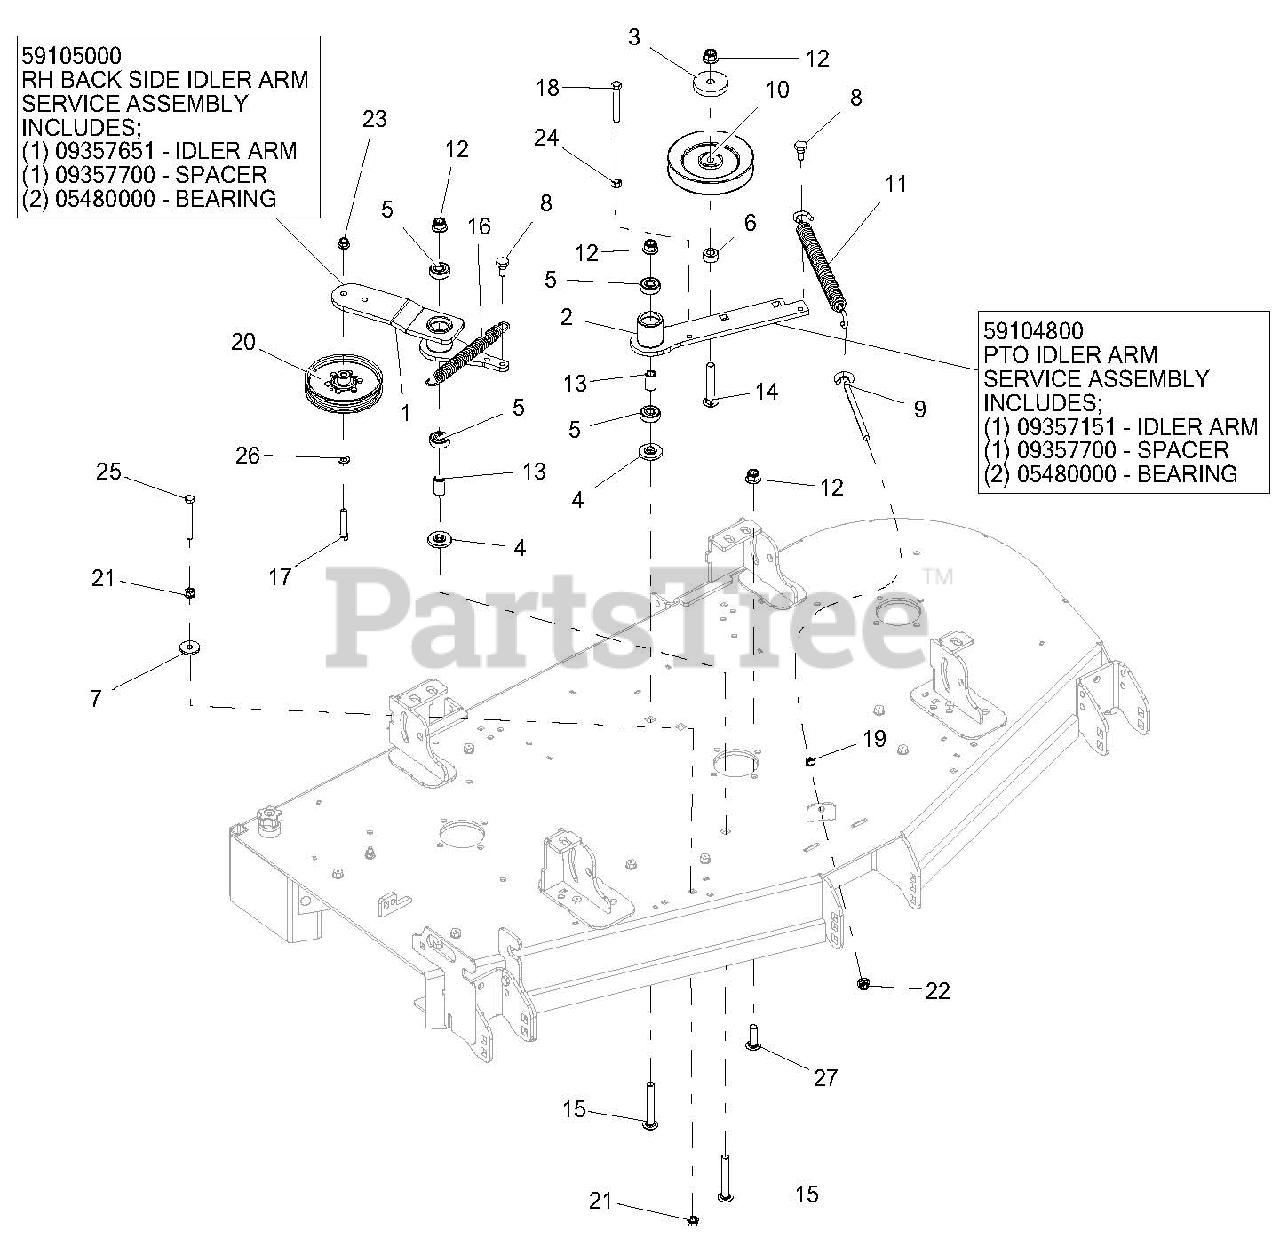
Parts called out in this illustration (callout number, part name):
1	WLDMT, DECK RH IDLER ARM
1	RH BACK SIDE IDLER ARM SERVICE ASSEMBLY
1	IDLER ARM
1	SPACER
1	BEARING
2	WLDMT, DECK PTO IDLER ARM-BLACK
2	PTO IDLER ARM SERVICE ASSEMBLY
2	IDLER ARM
2	SPACER
2	BEARING
3	CAP, IDLER BEARING SEALING
4	SPACER, IDLER ARM
5	BRG-BALL .500X1.375X.44
6	BSHG, SPCR .502 X .997.50 PM
7	WSHR-FL-STL .406X1.375X.135 YZ
8	BLT, SHLDR EP .38-16X.30 HEX YZ
9	BOLT, .38-16X6.00 .62 DIA EYE
10	SHEAVE, .50" ID X 6.00" OD V-IDLER
11	SPRG, EXTENSION
12	NUT-LK-NYL-FLG .50-13 YWZC
13	SPACER, .510 X .750 X 1.148
14	BLT-RDHDSQNK .50-13X3.00 G5Y
15	BLT-RDHDSQSHNK .50-13X3.25 YWZC
16	SPRG, EXTENSION .120X.845X6.55 WLD
17	BLT-HEX .38-16X2.00 GR5 YWZC
18	BLT-HEX .38-16X2.75 GR5 YWZC
19	NUT, JAM .375-16 YWZC
20	PULLEY, FLAT IDLER .500 X .375 W/BRG
21	@NUT-SPNLK-FLG .375-16 YWZC
22	NUT-LK-NYL-FLG .38-16 YWZC
23	NUT-LK-NYL-FLG .38-16 YWZC
24	NUT-HEX .38-16 YWZC
25	BLT-HEX .38-16X3.00 GR5 YWZC
26	WSHR-FL-STL.406X.812X.065 YWZ
27	BLT-RDHDSQSHNK .50-13X1.50 YWZC
